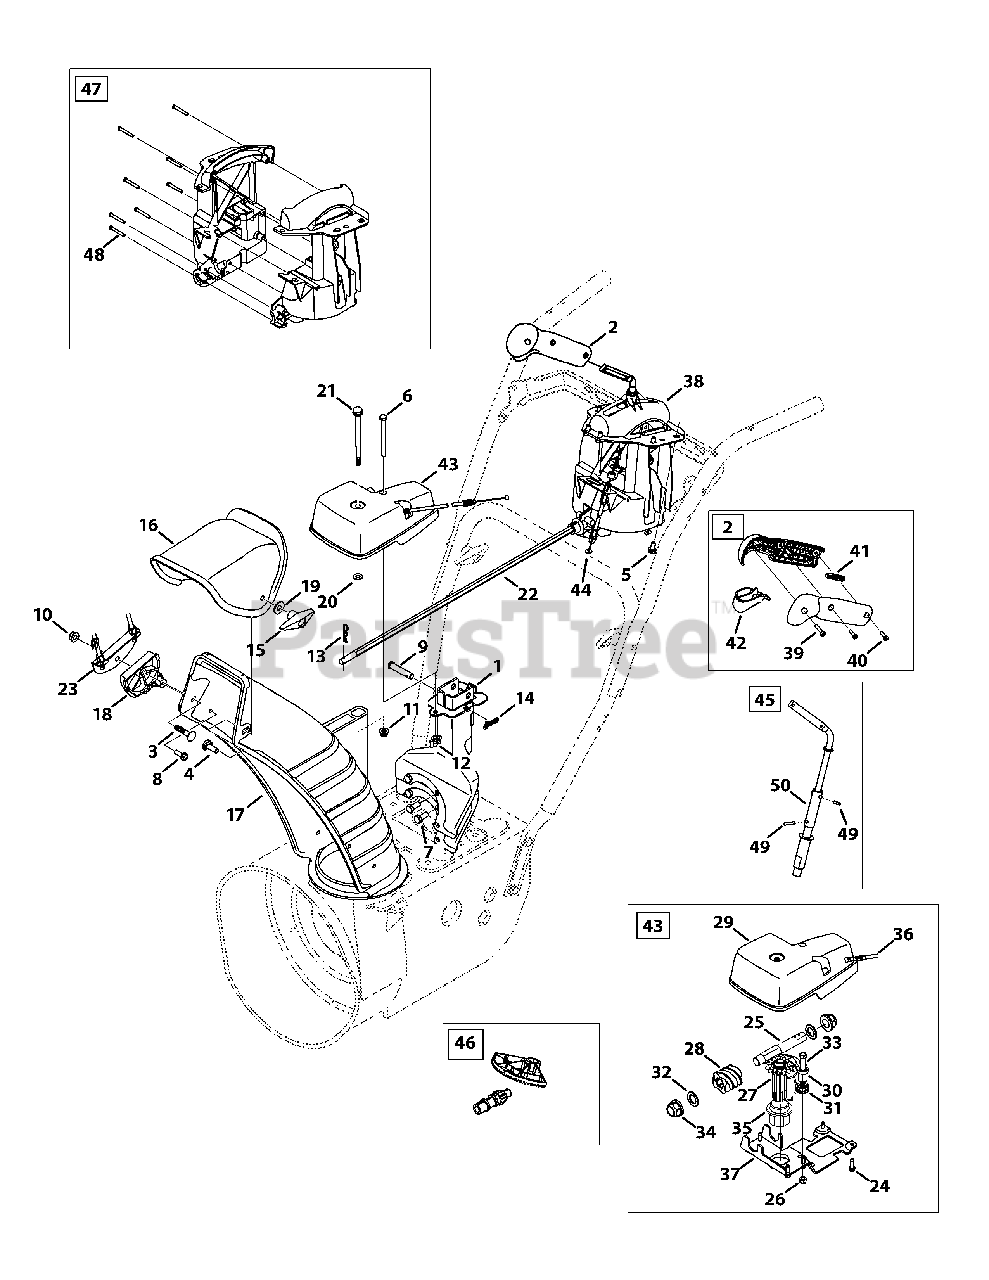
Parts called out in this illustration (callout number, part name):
1	Chute Support Bracket
2	Kit, Trigger Housing
3	Bolt, Carriage, 5/16-18 x 1.50
4	Bolt, Carrier, 5/16-18 x 1.00
5	Screw, Hi-Lo, 1/4-15 x 0.50
6	Hex Head Screw, 1/4-20 x 3.00
7	Hex Head Screw, 5/16-24 x .750
8	Screw, Hi-Lo, 1/4-15 x 0.750
9	Clevis Pin, 3/8 x 1.87
10	Nut, Flange Lock, 5/16-18
11	Nut, Flange Lock, 1/4-20
12	Wing Nut, 1/4-20
13	Internal Cotter Pin
14	Bow-Tie Cotter Pin
15	Wing Knob
16	Chute, Upper
17	Chute, Lower
18	Cable Guide, Chute Tilt
19	Washer, Flat, .349 x .879
20	Washer, Flat, .25 x .630
21	Screw, Shoulder, .312 x 3.5 x 1/4-20
22	Chute Rod, 3/8 Hex
24	Screw, 12-16 x .75
26	Hexlock Nut, 1/4-28
27	Gear, 14 T
28	Worm
29	Gear Cover
30	Pawl Lock
31	Torsion Spring, .721 ID x .474
32	Washer, Flat, .625 x 1.0 x .067
33	Screw, Shoulder, .34 x .95 x 1/4-28
34	Hex Bearing
35	Flange Bearing
37	Gear Bracket
38	Chute Control, 4-Way
39	Screw, #8 x 1.00
40	Screw, 8-32 x .750
41	Joystick Plug
42	Joystick Trigger
43	Chute Rotation Gearbox
44	4-Way Cable
44	4-Way Cable w/Clip
45	Shift Assembly
46	Gear Set Assembly
47	Handle Housing Assembly
48	Screw, #8-18 x 1.250
50	Block, Asm Joint
